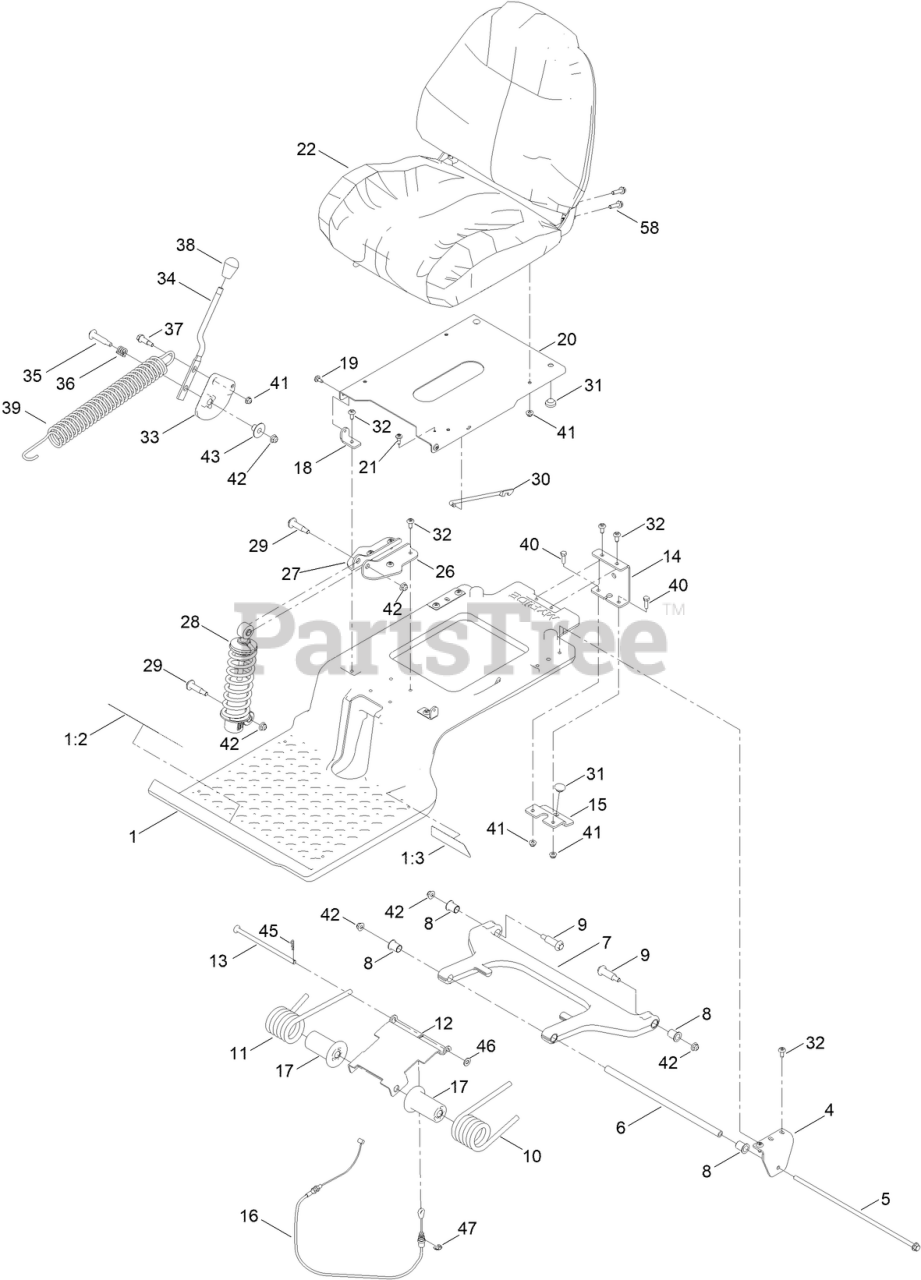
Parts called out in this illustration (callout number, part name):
1	SUBFRAME ASM
1:2	DECAL-DANGER
1:3	DECAL-MYRIDE
4	BRACKET-MOUNT, SWING ARM
5	SCREW-HHF
6	TUBE-SPACER
7	ARM, SWING
8	BUSHING-FLANGE
9	BOLT-SHOULDER
10	SPRING-TORSION, LH
11	SPRING-TORSION, RH
12	PLATE-ADJUSTER
13	ROD-ADJUSTMENT
14	BRACKET-CABLE
15	BRACKET LOWER
16	CABLE-ADJUSTMENT, MYRIDE
17	RETAINER-SPRING
18	BRACKET-SEAT
19	SCREW-SHOULDER
20	PAN-SEAT [BLACK]
21	SCREW-SHOULDER
22	SEAT ASM
26	BRACKET-SHOCK MOUNT, UPPER (LH)
27	BRACKET-SHOCK MOUNT, UPPER (RH)
28	SHOCK/SPRING ASM
29	BOLT-SHOULDER
30	ROD-PROP, SEAT
31	BUMPER-SEAT
33	PULLEY - CAM
34	LEVER - ADJUSTMENT
35	BOLT-SHOULDER
36	SPRING-COMPRESSION
37	BOLT-SHOULDER, HHF
38	KNOB-MR
39	SPRING-EXTENSION
40	SCREW-HH
41	NUT-HF
42	NUT-HF, NI
43	BUSHING - FLANGE
45	PIN-HAIR
46	WASHER-FLAT
47	RING-RETAINING, EXTERNAL
58	SCREW-HHF
